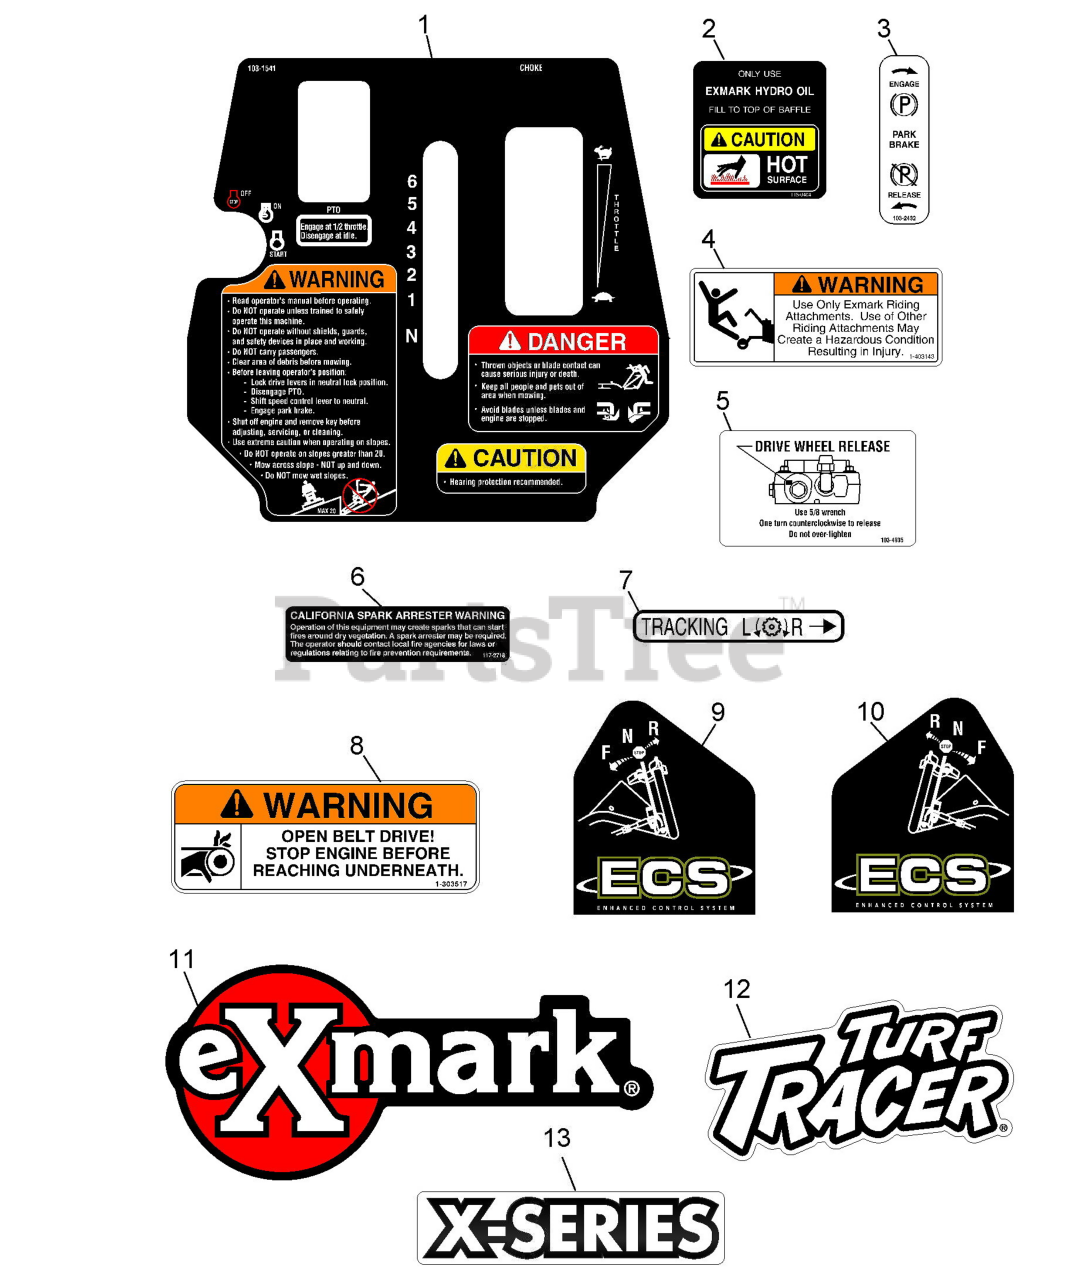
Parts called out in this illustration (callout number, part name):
1	DECAL,TTH ECS CONSOLE
2	DECAL-HYDRAULIC TANK
3	DECAL,SULKY WARNING
4	DECAL,PARKING BRAKE
5	DECAL,DRIVE RELEASE
6	DECAL-ARRESTER, SPARK
7	DECAL,TRACKING ADJUST
8	DECAL,BELT DRIVE
9	DECAL,LH ECS INSTRUCTION
10	DECAL,RH ECS INSTRUCTION
11	DECAL,EXMARK LOGO
12	DECAL,TTH MODEL
13	DECAL-X-SERIES
